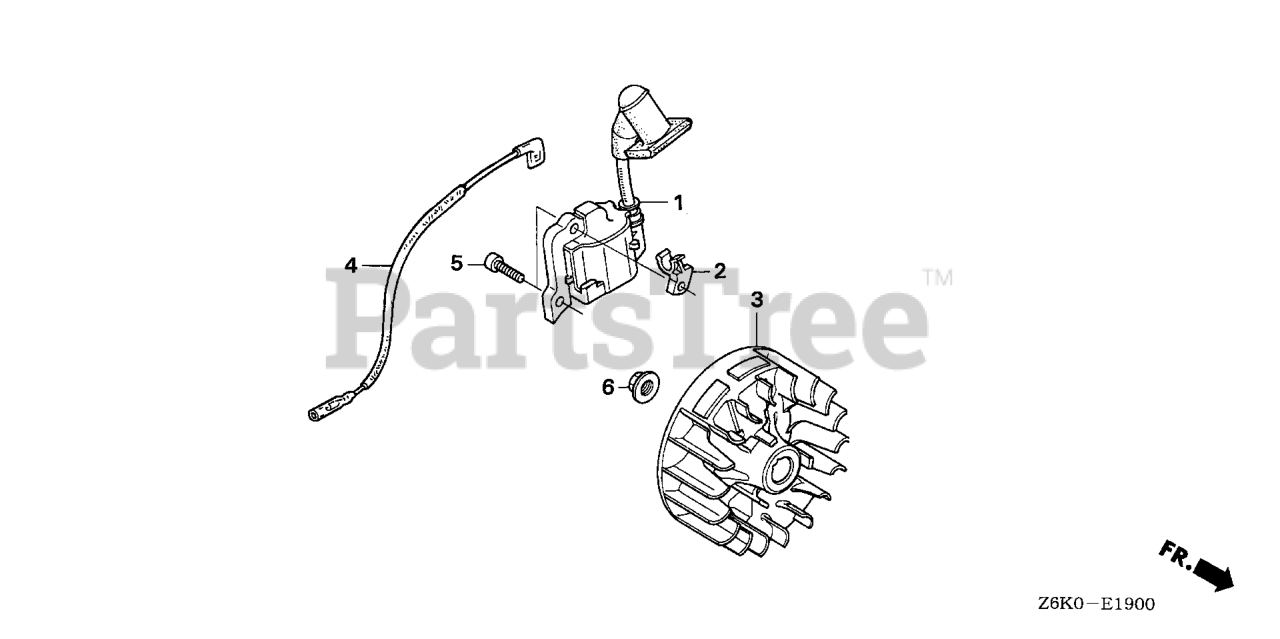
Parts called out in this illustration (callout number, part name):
1	COIL ASSY., IGNITION
2	CLIP, IGNITION WIRE
4	WIRE, STOP SWITCH
5	BOLT, SOCKET (4X14)
6	NUT, FLANGE (8MM)
